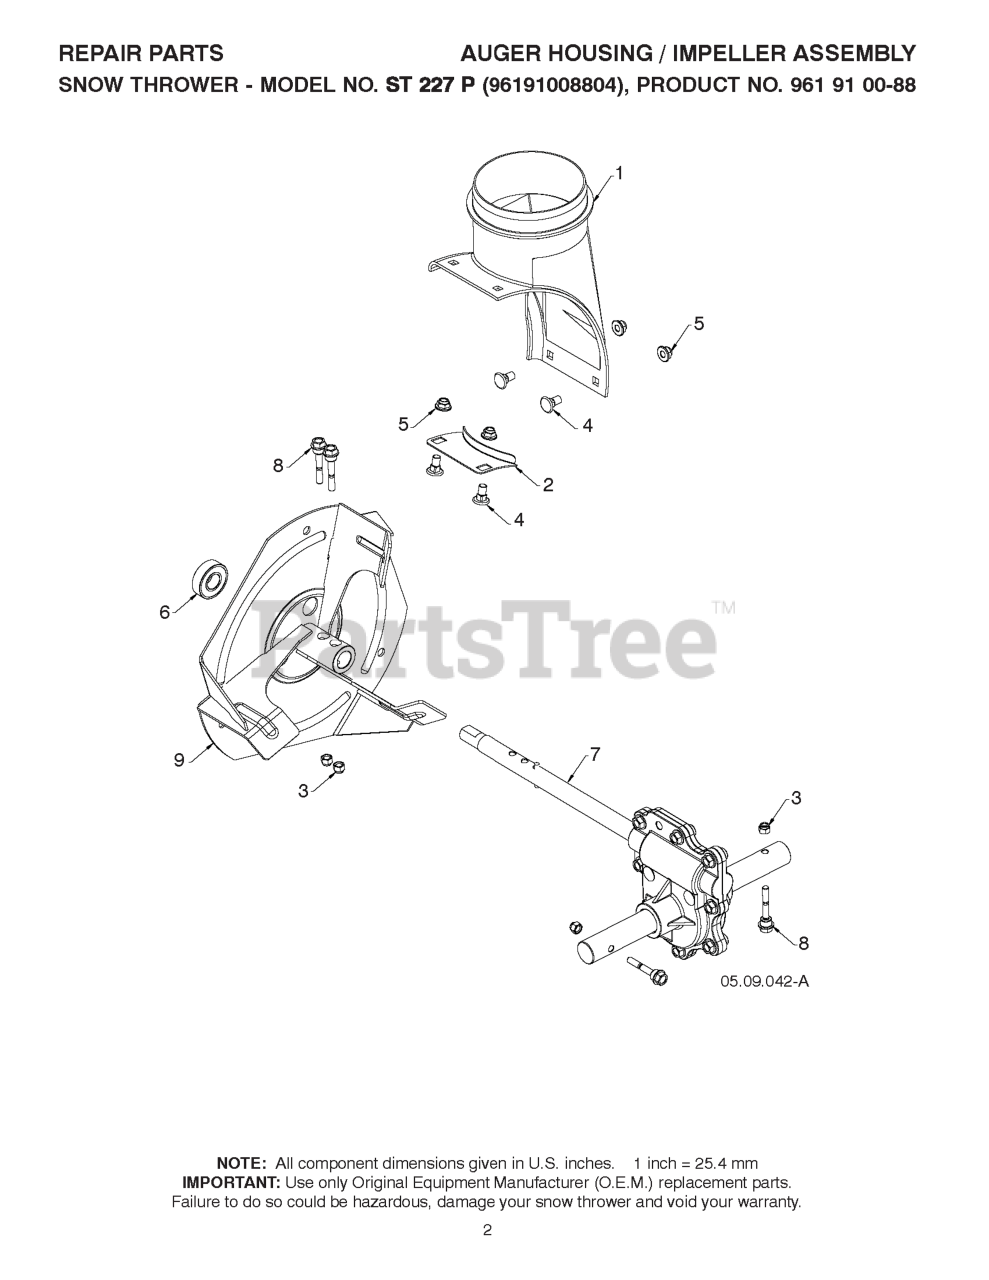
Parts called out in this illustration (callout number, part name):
1	CHUTE.DISCHARGE.BASE
2	BRACKET, CORNER DISCHARGE
3	LOCKNUT.NYLOC.1/4-20
4	BOLT CARR WAFER BLK 5_16-18 X
5	NUT HEX FLG NYLOCK BLK 5_16-1
7	TRANSMISSION.GEARBOX.ALUM.DD
8	BOLT.1/4-20 X 1-13/16 SHEAR
9	IMPELLER.STEEL.SNOW.BLACK
